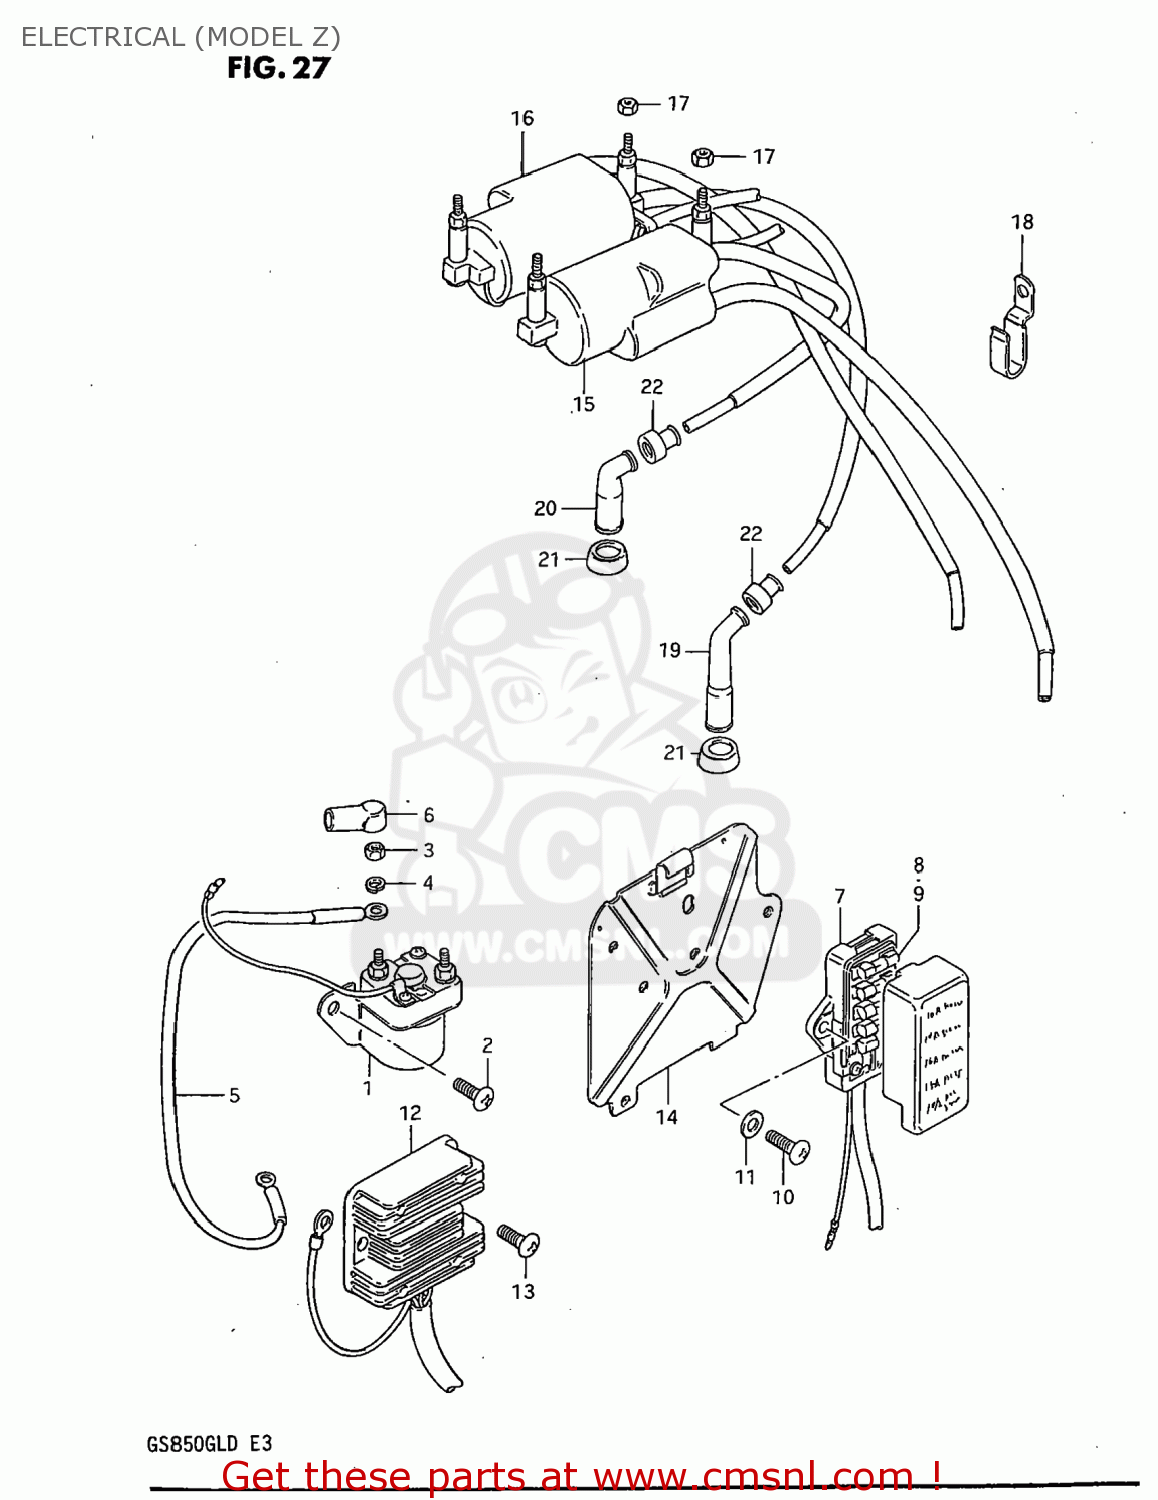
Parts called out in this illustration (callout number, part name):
1	RELAY ASSY,STARTING MOTOR
2	SCREW
3	NUT 6MM
4	LOCK WASHER
5	WIRE,STARTER MOTOR LEAD
6	CAP,STARTER RELAY
7	BOX ASSEMBLY,FUSE
8	FUSE(10A)
9	FUSE(15A)
10	SCREW 6X12
11	WASHER
12	RECTIFIER ASSEMBLY
13	SCREW 6X12
14	HOLDER COMP,ELECTRONIC PARTS
15	COIL ASSEMBLY,IGNITION
16	COIL ASSEMBLY,IGNITION
17	NUT
18	CLAMP
19	CAP ASSY,SPARK PLUG
20	CAP,SPARK PLUG
21	SEAL,SPARK PLUG
22	SEAL,SPARK PLU
